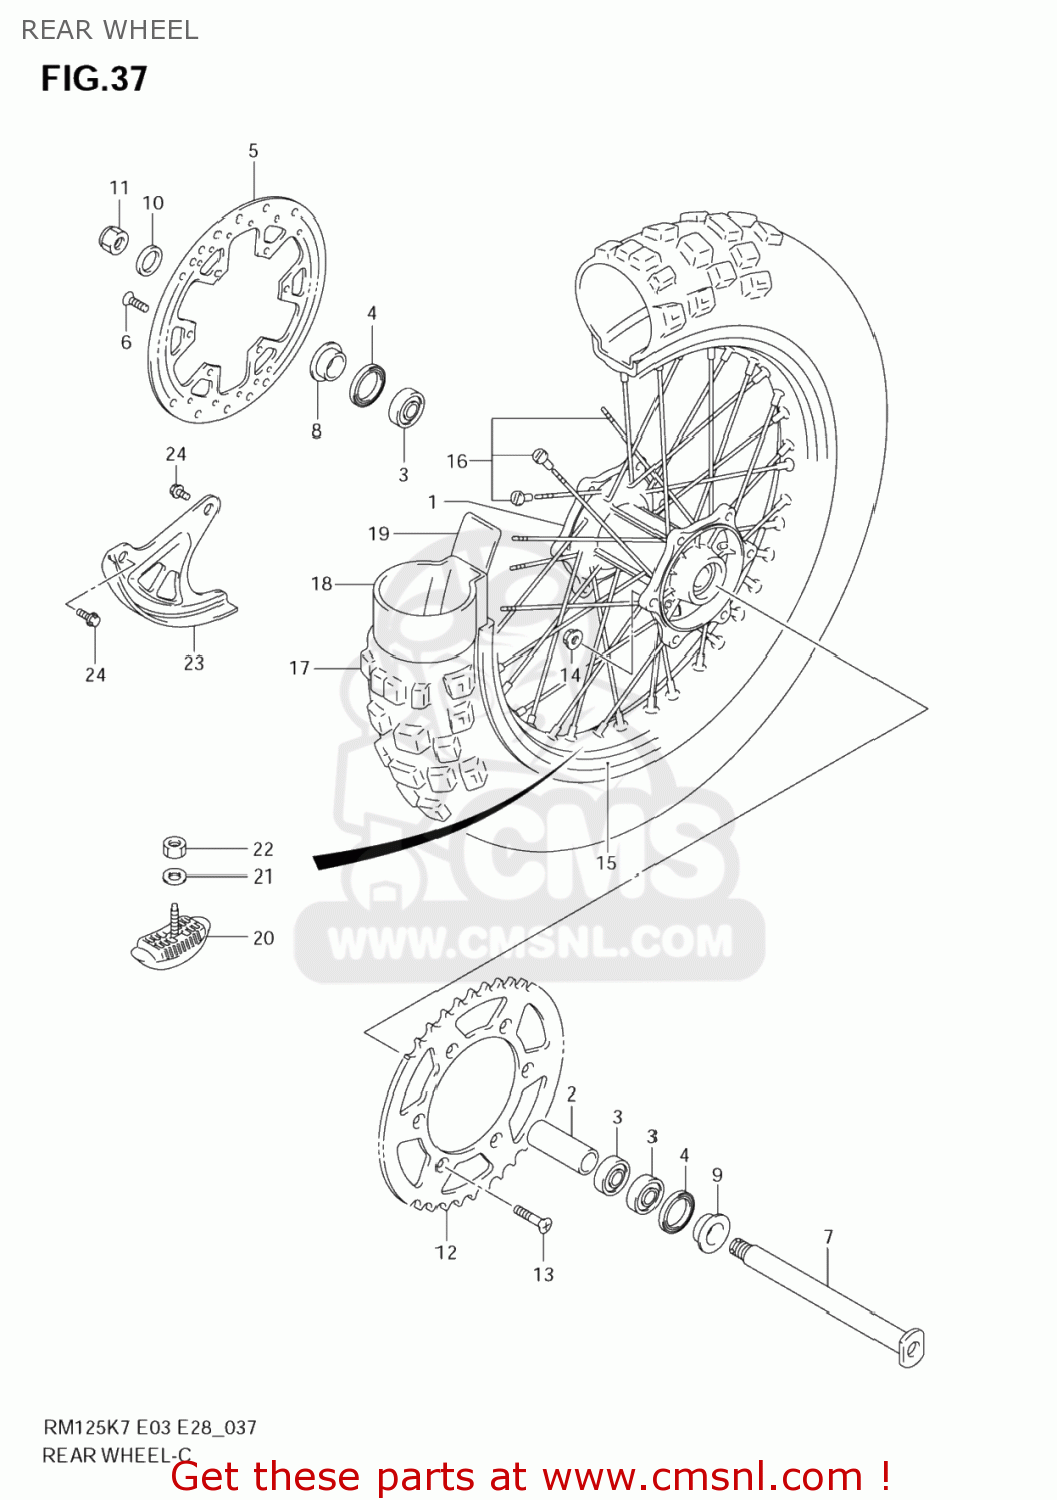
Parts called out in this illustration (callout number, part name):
1	HUB,RR WHEEL
2	SPACER,RR HUB BEARING
3	BEARING(22X44X12)
4	SEAL,OIL(30X44X7)
5	DISC,RR BRAKE
6	BOLT(6X12)
7	AXLE,RR
8	SPACER,RR AXLE
9	SPACER,RR AXLE
10	WASHER(19X32X3.2)
11	NUT
12	SPROCKET,RR(NT:48)
13	BOLT(8X28)
14	NUT
15	RIM,RR WHEEL(1.85X19 AL)
16	SPOKE SET,RR WHEEL
17	TIRE,RR(100/90 19)
18	TUBE
19	PROTECTOR,WHL INR TUBE
20	STOPPER,BEAD(1.85)
21	WASHER
22	NUT
23	COVER,REAR DIS
24	BOLT(6X12)
